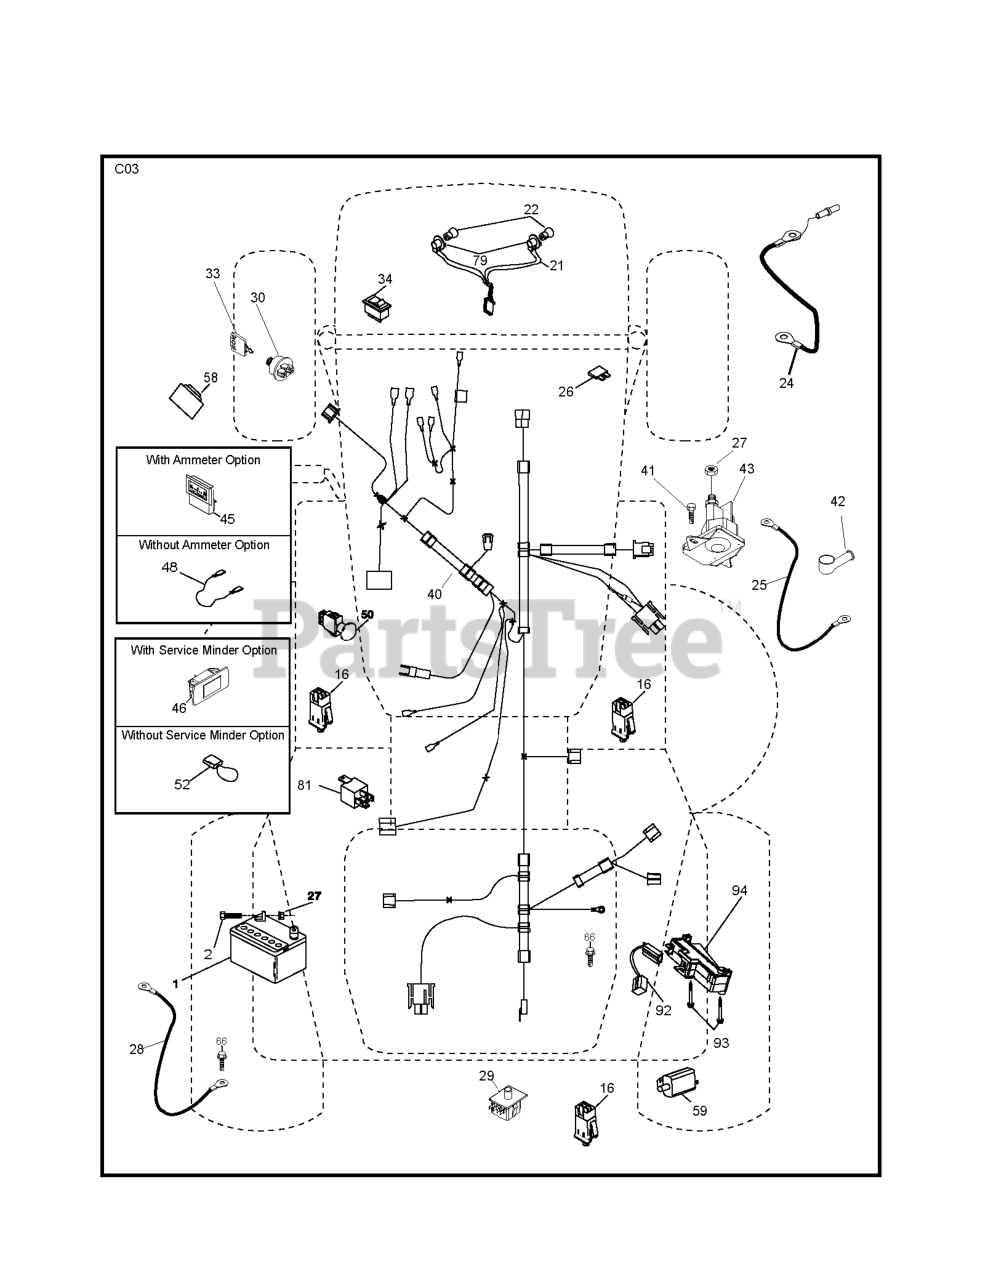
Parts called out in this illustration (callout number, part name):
1	Battery 12 Volt 25 Amp
2	BOLT.HEX.1/4.X.3/4.DICHROMATE
16	SWITCH INTERLOOK PUSH-IN
21	HARNESS.LIGHT W/4152J BULBS
24	BATTERY CABLE GT
25	CABLE BATTERY
26	FUSE 20AMP
27	NUT
28	CABLE GROUND
29	SWITCH.SEAT.DP W/RAMPS
30	SWITCH.IGN.DELTA.W.LGH.ROS
33	KEY.CHAIN.BLISTER.PACK.GEN.INT
40	RP HARNESS.IGN.ELECT.REG.CRD
41	BOLT
42	TERMINAL COVER
43	SOLENOID.W/BRASS.PLUNGER
48	ADAPTER.AMMETER
50	RP.PTO.SWITCH.8 TERMINAL.BLACK
52	WIRE PROTECTION LOOP
58	BUZZER
59	.WITCH.FULL BAGGER.INDICATOR
79	BULB HOLDER ASM.
81	RELAY.ASSY.T
92	HARNESS.PIGTAIL.CONSLE
93	SCREW.PLASTITE
94	MODULE.REVERSE.ROS
